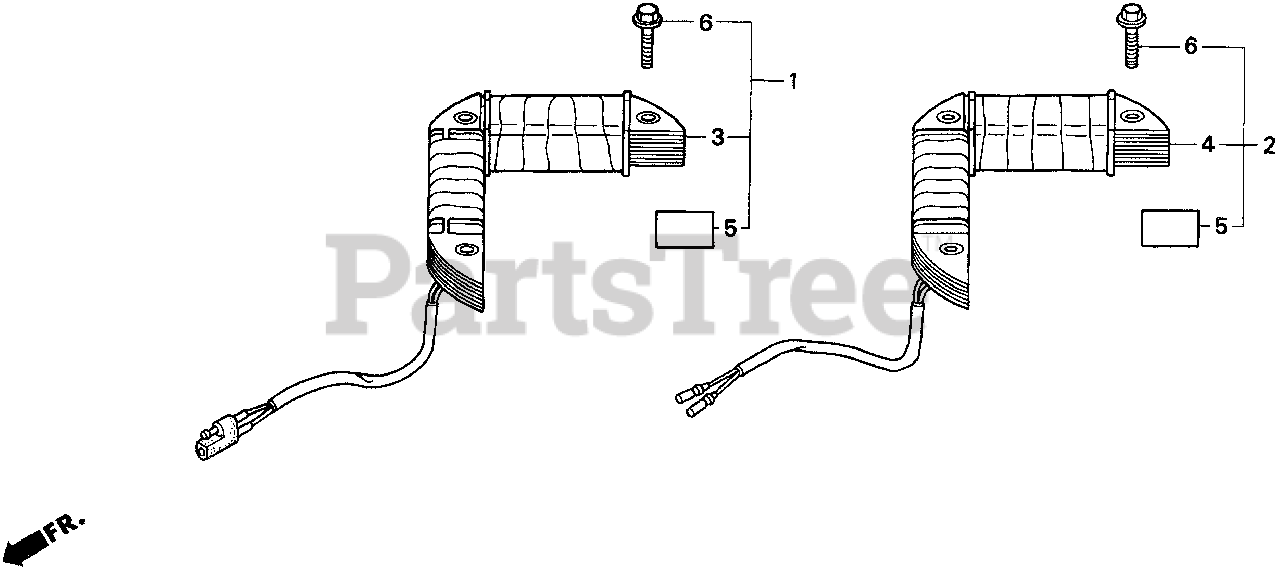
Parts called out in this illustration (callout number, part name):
2	COIL KIT, CHARGE (10A)
4	COIL ASSY., CHARGE (12V-10A)
5	MARK, RECEPTACLE (10A) Use up to Engine SN 1210123.
5	MARK, RECEPTACLE (10A) Use from Engine SN 1210124.
6	BOLT, FLANGE (6X32)
